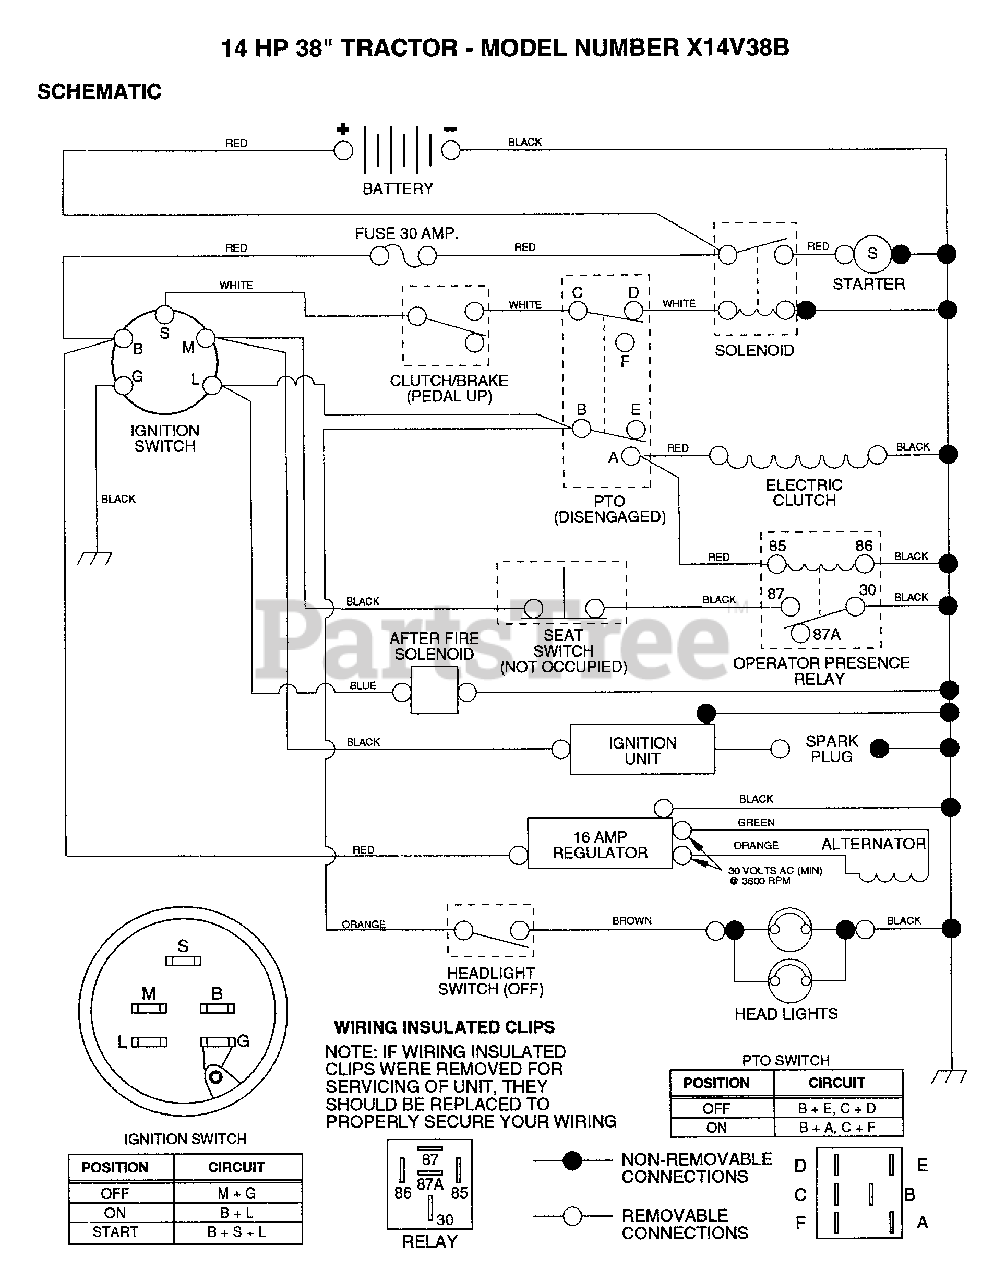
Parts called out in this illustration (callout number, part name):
1	VALVE CAP
3	HOOD DECAL RH
3	FITTING LT
5	TUBE.18X9.5-8
5	TUBE.5.3/4.5/6
6	DECAL, FENDER
6	VALVE STEM LT
7	HUB CAP
8	DECAL CAUTION
8	"FLANGE, BEARING"
9	DECAL T
9	WASHER
10	"DECAL,STR WHL "
11	DECAL WARNING
12	DECAL YT
13	DECAL, SPEED/DECK SIZE, CHASSIS
15	"DECAL,GRILL "
16	DECAL.ENG.805719
17	REFLECTOR, TAILLIGHT
